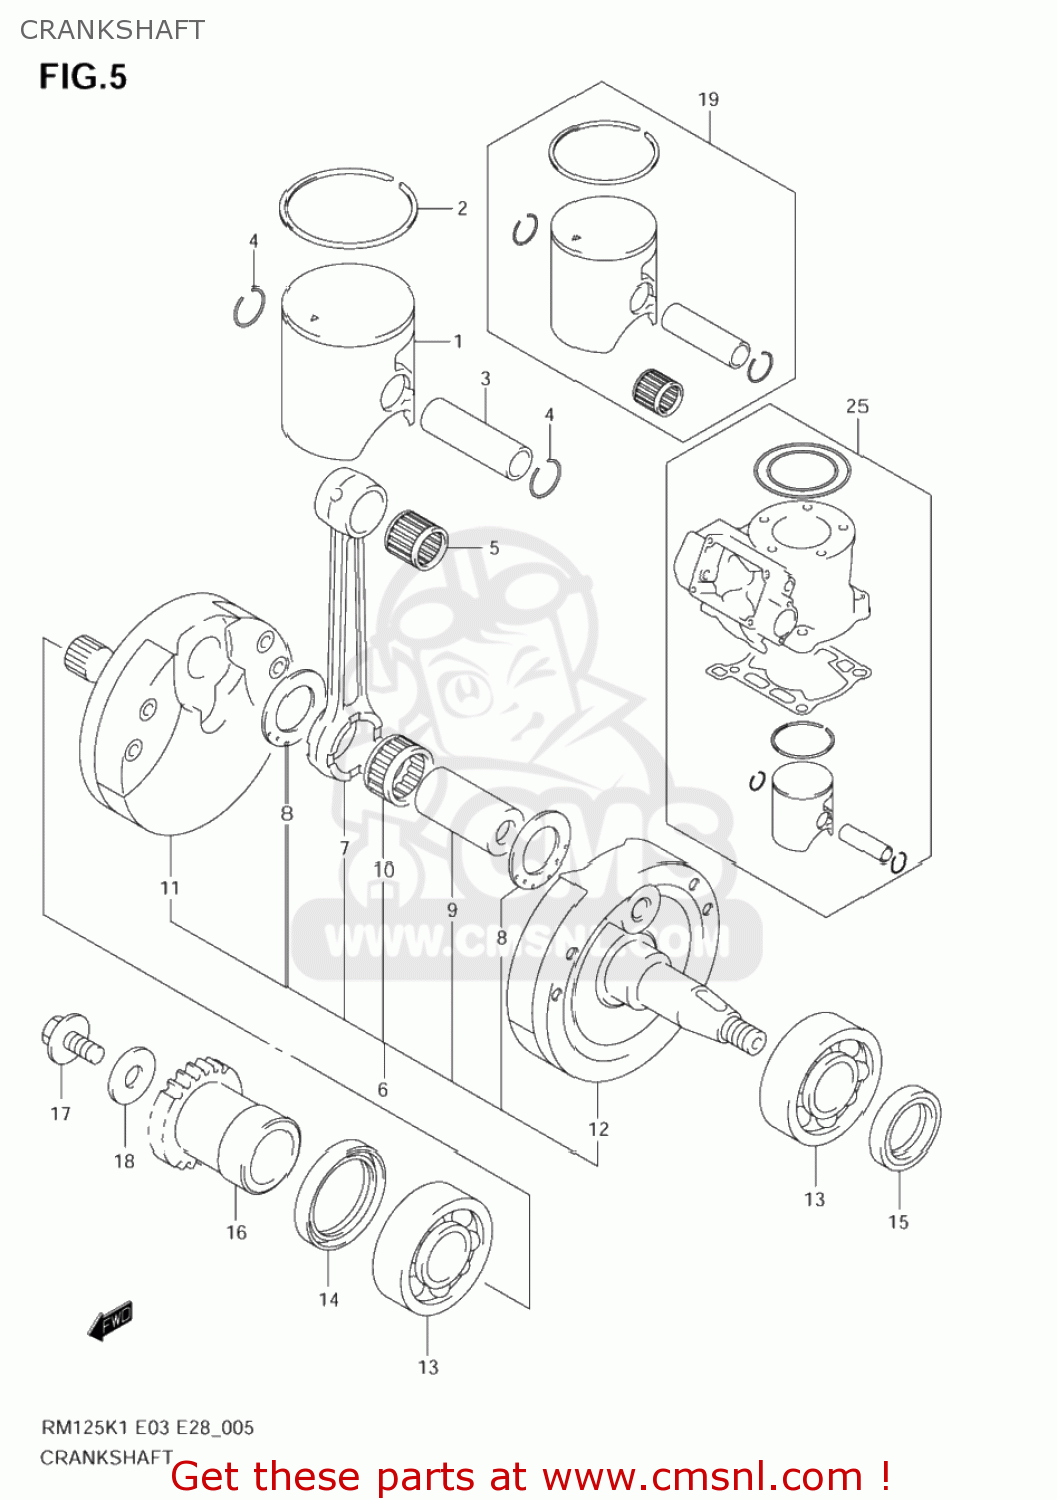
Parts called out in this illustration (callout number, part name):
1	PISTON
2	RING,PISTON
3	PIN,PISTON
4	CIRCLIP
5	BEARING(15X19X20)
6	CRANKSHAFT ASSY
7	CONNROD
8	WASHER(22X36X1)
9	PIN,CRANK
10	BEARING(22X28X16)
11	CRANKSHAFT,R
12	CRANKSHAFT,L
13	BEARING(22X56X16)
14	SEAL,OIL(30X40X7)
15	SEAL,OIL(18X30X7)
16	GEAR,PRIMARY DRIVE
17	BOLT(10X20)
18	WASHER
19	PISTON KIT
20	PISTON
21	RING,PISTON
22	PIN,PISTON
23	BEARING(15X19X20)
24	CIRCLIP
25	TOP END KIT,ENGINE
26	O RING,CYLINDER HEAD NO.1
27	O RING,CYLINDER HEAD NO.2
28	GASKET,CYLINDER (NAS)
29	PISTON
30	RING,PISTON
31	CIRCLIP
